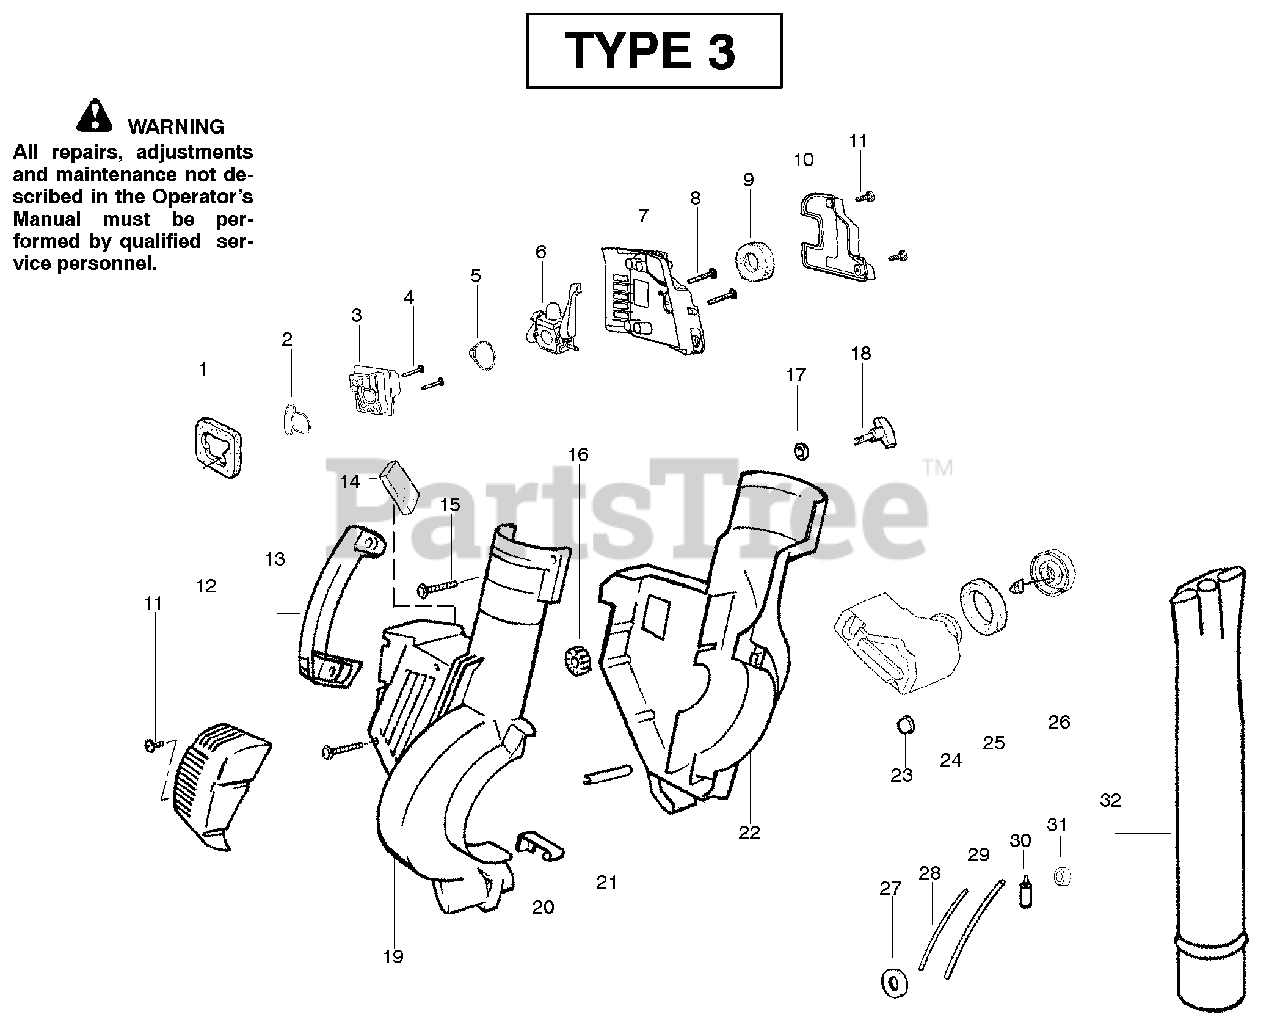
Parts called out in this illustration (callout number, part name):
1	Air Dam (kit)
2	Gasket-Adapter (kit)
3	Carburetor Adaptor
5	Gasket-Carburetor (kit)
6	Kit-Carb Ass'y. (C1Q-W11C)
6	Kit-Carb Ass'y. (WT-606)
8	Screw-Carb.
9	Filter-Air
10	Cover-Air Filter
12	Guard-Muffler
14	Foam 71.12mm (Kit)
16	Isolator
18	Knob-Blower
19	Assy.-Housing Right
20	Spring-Cover Latch
21	Guide-Starter Rope
22	Housing-Left
23	Isolator-Crankcase
24	Assy-Fuel Tank
25	Gasket-Fuel Tank
26	Fuel Cap w/Retainer
27	Grommet-Shroud
28	Kit-Line Carb/Purge
29	Kit-Line Tank/Purge
30	Assy-Fuel Pick-up
31	Grommet-Fuel line (kit)
32	Tube-Blower
